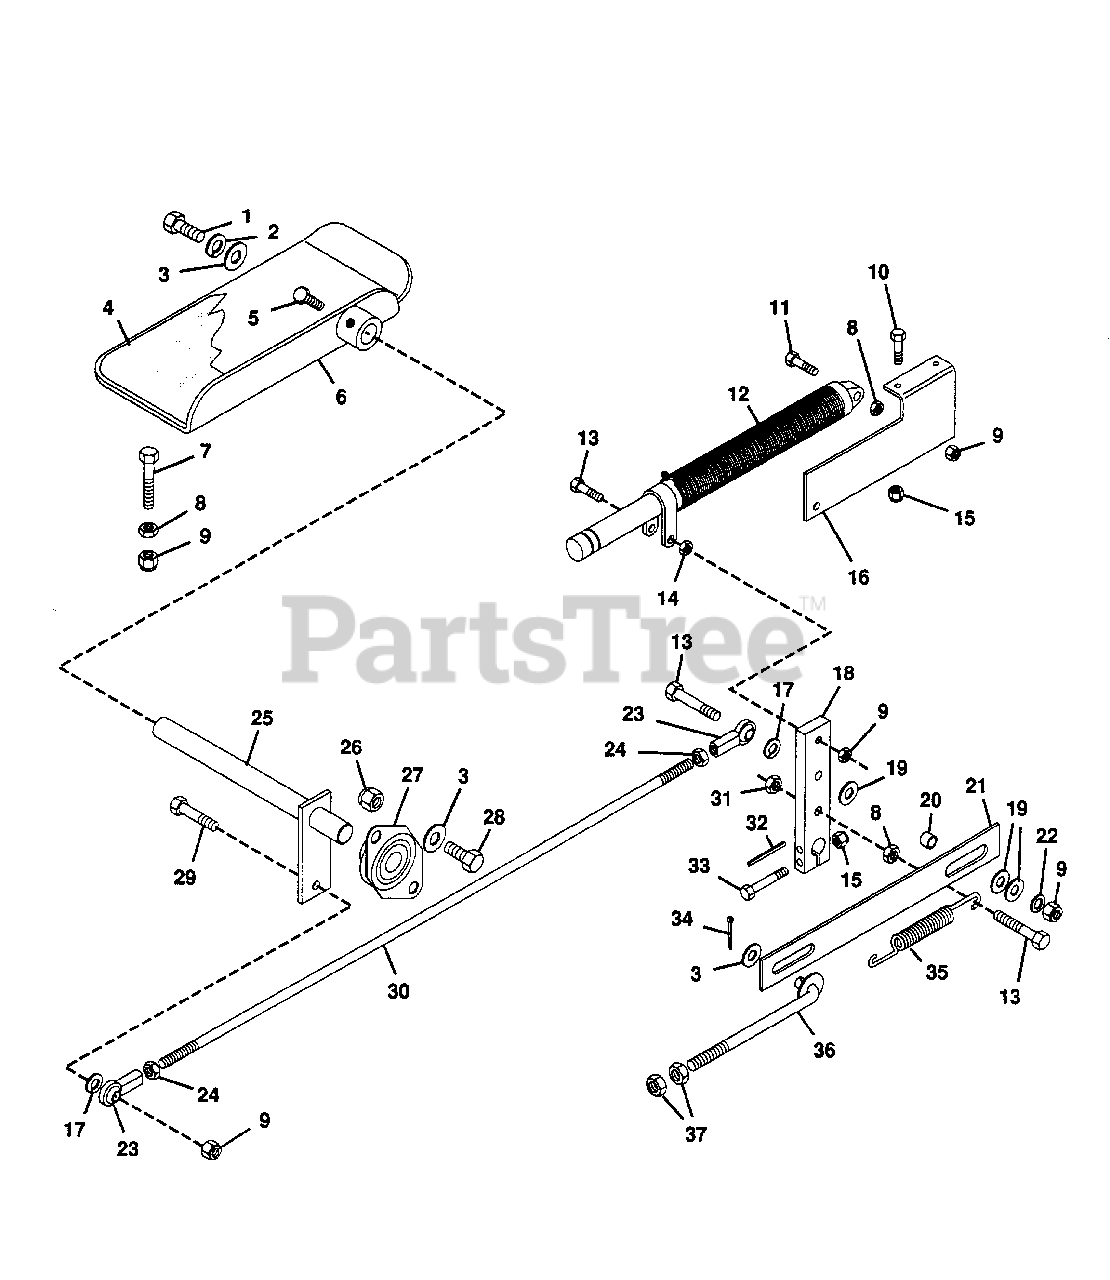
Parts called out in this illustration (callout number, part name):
1	Bolt, Hex 3/8-16x1.00
2	Washer, Lock 3/8 Reg.
3	Washer, Flat .406x.812x.065
4	Cover, Large Footboard
5	Bolt, Hex 1/4-28x.50
6	Weldment, Foot Control Lever
7	Bolt, 5/16-18x2.50 All Thread
8	Nut, Hex 5/16-18
9	Nut, Lock 5/16-18
10	Bolt, Hex 1/4-20x.625
11	Bolt, Hex 5/16-18x1.75
12	Damper
13	Bolt, Hex 5/16-18x2.00
14	Nut, Jam 5/16-18 Hex
15	Nut, Lock 1/4-20
16	Bracket, Damper
17	Washer, Lock 5/16 Reg.
18	Arm, Pump
19	Washer, Flat .531x1.062x.095
20	Bush., St. .328x.500x.500 Stl.
21	Strap, Neutral Detent
22	Washer, Flat .344x.688x.065
23	Rod End, 5/16 Female
24	Nut, Jam 5/16-24 Hex
25	Weldment, Control
26	Nut, Lock 3/8-16
27	Bearing, Fan
28	Bolt, Hex 3/8-16x.75
29	Bolt, Hex 5/16-18x1.25
30	Rod, Speed Control
31	Nut, Lock 5/16-18
32	Pin, Spring .250x1.000
33	Bolt, Hex 1/4-20x1.75
34	Pin, Cotter .094x.75
35	Spring, Extension 5.5x.5x 20 Rate
36	Weldment, Detent Rod
37	Nut, Hex 3/8-24
